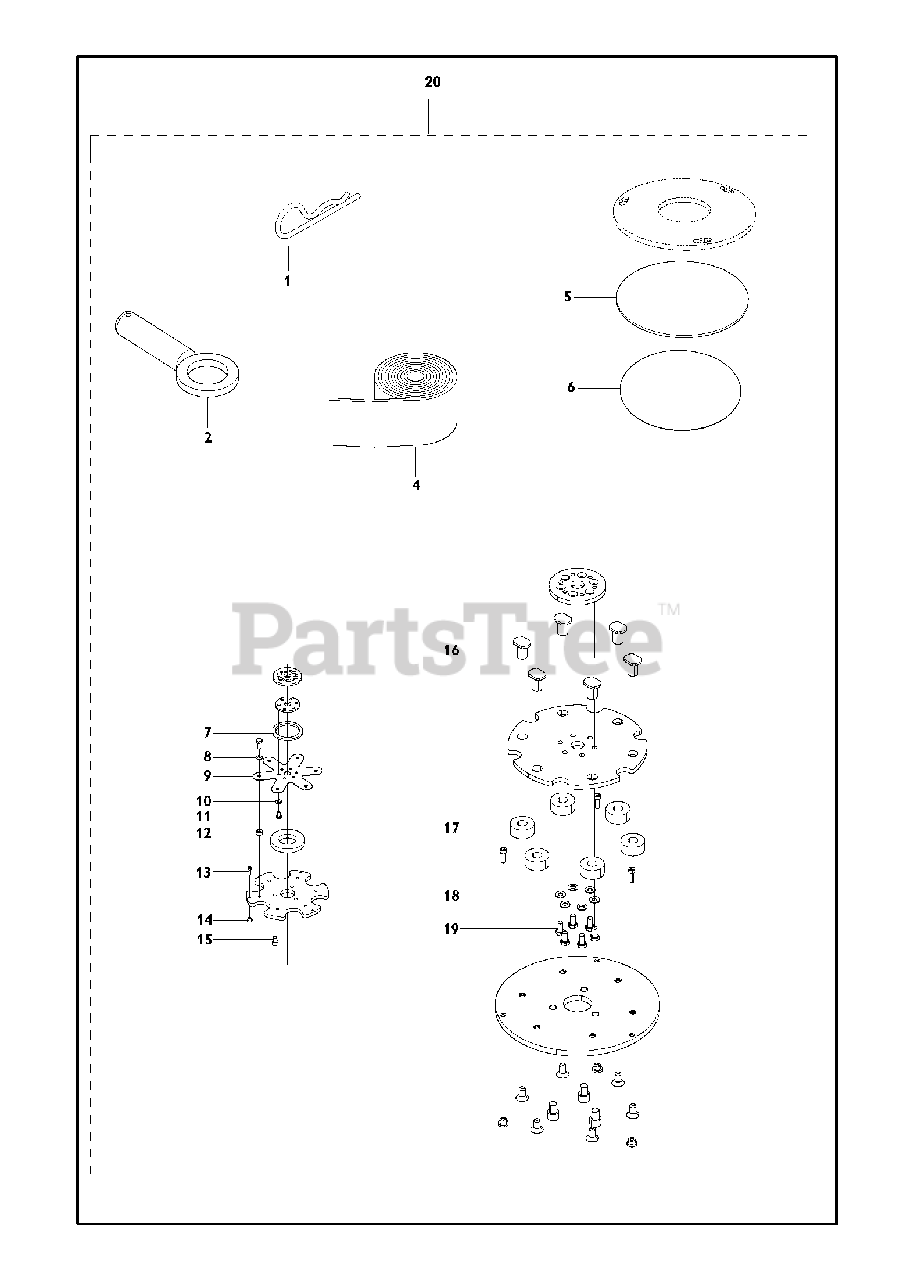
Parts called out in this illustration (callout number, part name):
1	SPRING COTTER
8	WASHER
10	WASHER
18	WASHER
